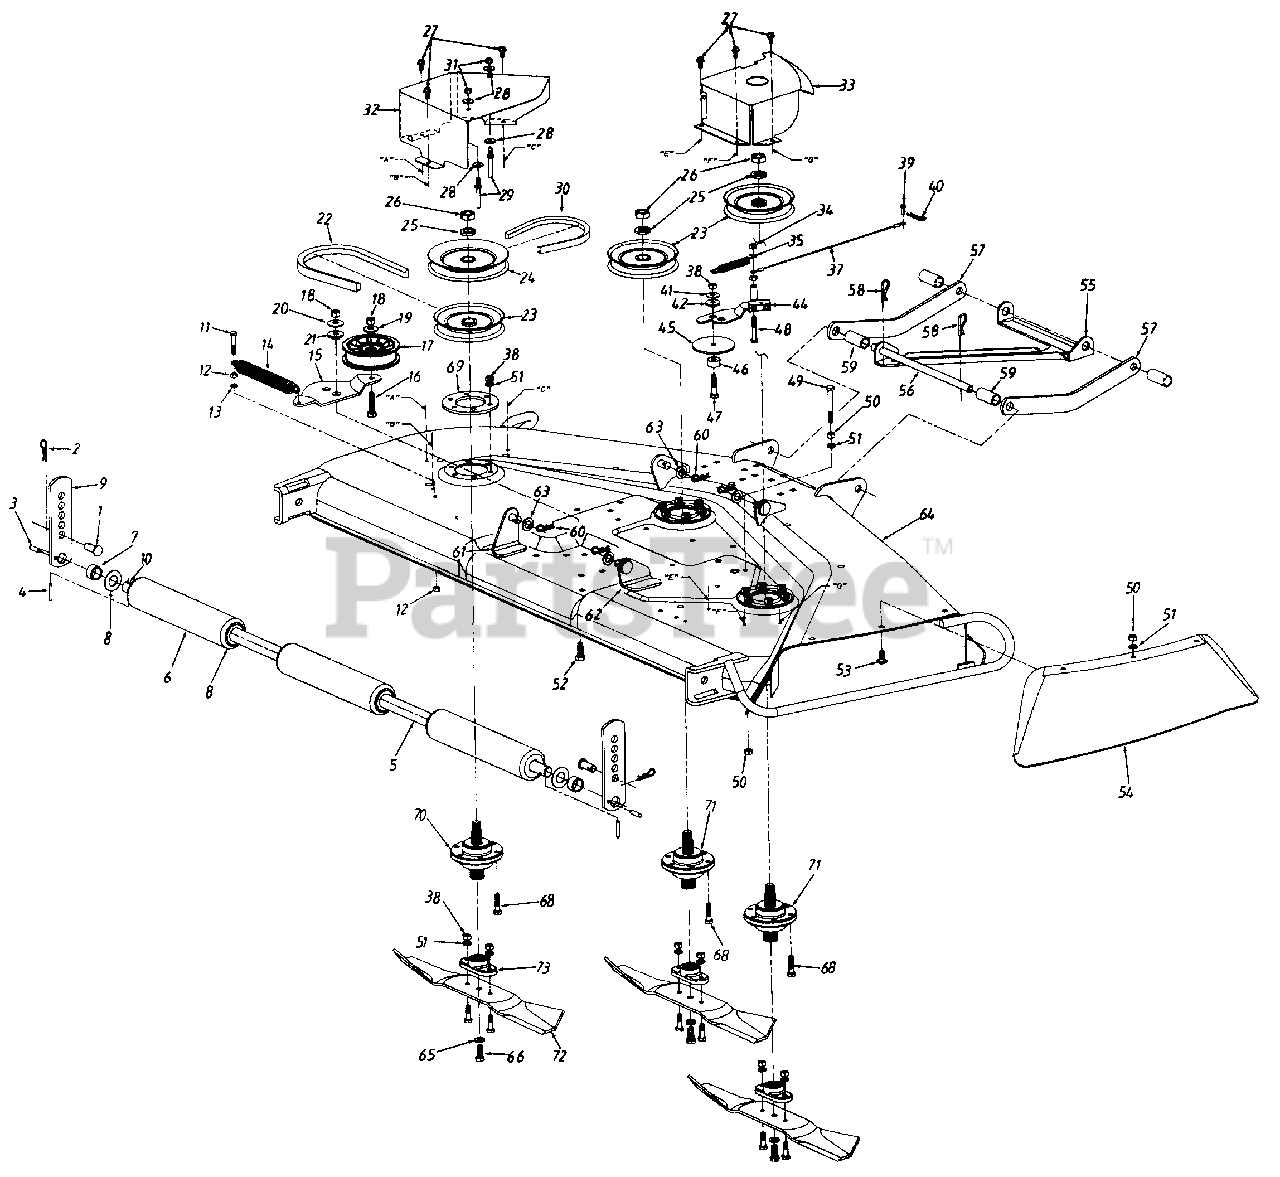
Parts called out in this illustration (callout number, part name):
1	Clevis Pin
2	Hairpin Clip
3	Spring Pin 1/4" x 1" Lg.
4	Spring Pin 3/16" x 1-14" Lg.
7	Spacer .75" I.D.
8	Fl-Wash. .76" I.D. x 1.5" O.D.
10	Roller Shaft
11	Hex Bolt 1/4-28 x 1.5" Lg. (Gr. 5)
12	Hex Nut 1/4-28 Thd.
13	L-Wash. 1/4" I.D.
14	Ext. Spring 7.33" Lg.
17	Idler Pulley
18	Hex Nut 3/8-24 Thd.
19	Bell-Wash. 3/8" I.D.
20	Bell-Wash. .39" I.D. x 1.13" O.D.
21	Shld. Spacer .625" I.D.
22	"V"-Belt
23	Deck Pulley
24	Upper Deck Pulley
25	L-Wash. 5/8" I.D.
26	Hex Jam Nut 5/8-18 Thd.
27	Hex Wash. Hd. Scr. 1/4-20 x .5" Lg.
28	Bell-Wash. 1/4" I.D.
29	Belt Guard Pin
30	"V"-Belt
31	Hex Nut 1/4-20 Thd.
35	Ext. Spring 3.97" Lg.
37	Brake Cable
38	Hex Nut 5/16-24 Thd.
39	Clevis Pin
40	Hairpin Clip
41	Bell-Wash. .325" I.D.
42	Shld. Spacer
44	Brake Ass'y.
45	Fl-Wash. 5/16" I.D. x .3" O.D.
46	Spacer .44" Lg.
47	Hex Bolt 5/16-24 x 1.5" Lg. (Gr. 5)
48	Hex Bolt 1/4-28 x 1.75" Lg. (Gr. 5)
49	Hex Bolt 5/16-18 x 2.5" Lg.
50	Hex Nut 5/16-18 Thd.
51	L-Wash. 5/16" I.D.
52	Hex Bolt 3/8-24 x 1" Lg.
53	Carr. Bolt 5/16-18 x .75" Lg.
59	Spacer 1.75" Lg.
60	Hairpin Clip
63	Fl-Wash. 1/2" I.D. x .93" O.D.
66	Hex Bolt 3/8-24 x .88" Lg. (Gr. 5)
68	Hex Bolt 5/16-24 x 1-1/4" Lg. (Gr. 5)
69	Spindle Reinforcement Plate
70	Spindle Ass'y. (L.H.)
71	Spindle Ass'y. (R.H. & Center)
72	Blade
73	Blade Adapter
12649-0638	GUARD-CHUTE - MTD/TROY-BILT RED (0638)
12649-0648	GUARD-CHUTE - TECH GRAY (0648)
12650-4008	Height Adjuster - WINE RED (4008)
